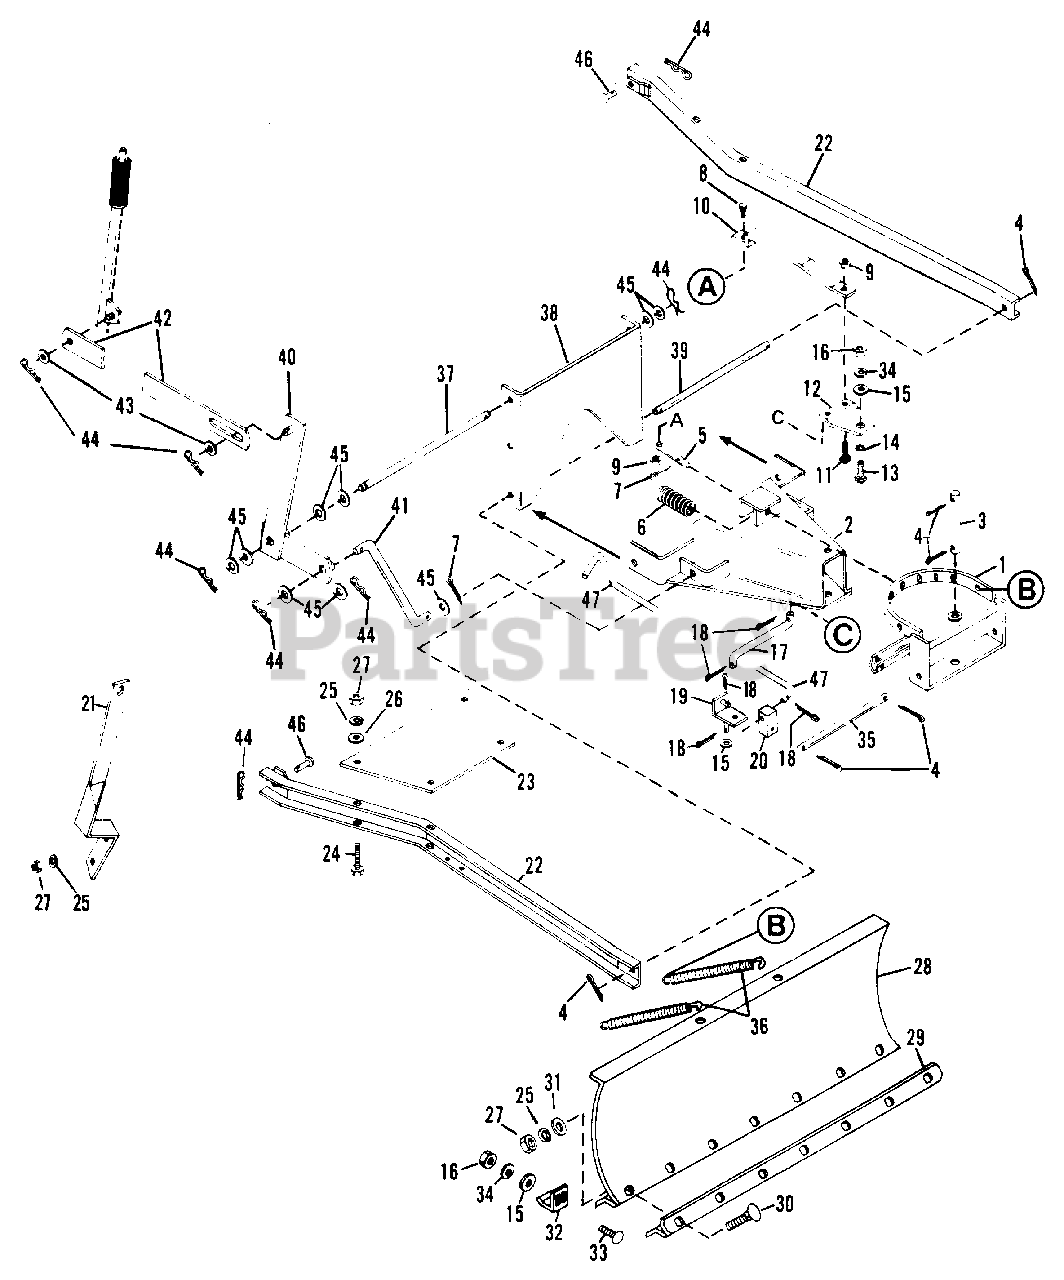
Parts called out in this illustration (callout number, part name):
1	SUPPORT
2	PUSH FRAME
3	ROD
4	COTTER PIN 3/16X1.25
5	LATCH PIN
6	COMP. SPRING
7	COTTER PIN 1/8X1.00
8	BOLT, HEX 5/16-18X1.25
9	NUT, LOCK 5/16-18
10	STRAP
11	BOLT, 5/16-18X.625 RD HD SQ NK
12	PIVOT PLATE
13	BOLT, HEX 3/8-16X1.00
15	WASHER, FLAT .438X1.000X.083
16	NUT, HEX 3/8-16
17	ROD
18	COTTER PIN 1/8X.75
20	UNIVERSAL BLOCK JOINT
21	CONTROL SUPPORT
22	CHANNEL
23	STIFFENER PLATE
24	BOLT, HEX 5/16-18X2.50
25	WASHER, LOCK 5/16 SP
26	WASHER, FLAT .312X.734X.065
27	NUT, HEX 5/16-18
28	BLADE
29	WEAR PLATE
30	BOLT, CARRIAGE 5/16-18X1.00
31	WASHER, FLAT .406X.812X.065
32	SKID SHOE
33	BOLT, 3/8-16X1.00 RD HD SQ NK
34	WASHER, LOCK 3/8 REG.
35	ROD
36	EXTENSION SPRING
37	MOUNT ROD
38	PIVOT SUPPORT
39	PIVOT ROD
40	LIFT BELLCRANK
41	LIFT LINK
42	LIFT STRAP
43	WASHER, FLAT .500X1.250X.083
44	HAIR PIN, INTERNAL
45	WASHER, FLAT .656X1.312X.095
46	CLEVIS PIN
47	CONTROL ROD
NS	DECAL, GRAVELY LOGO
